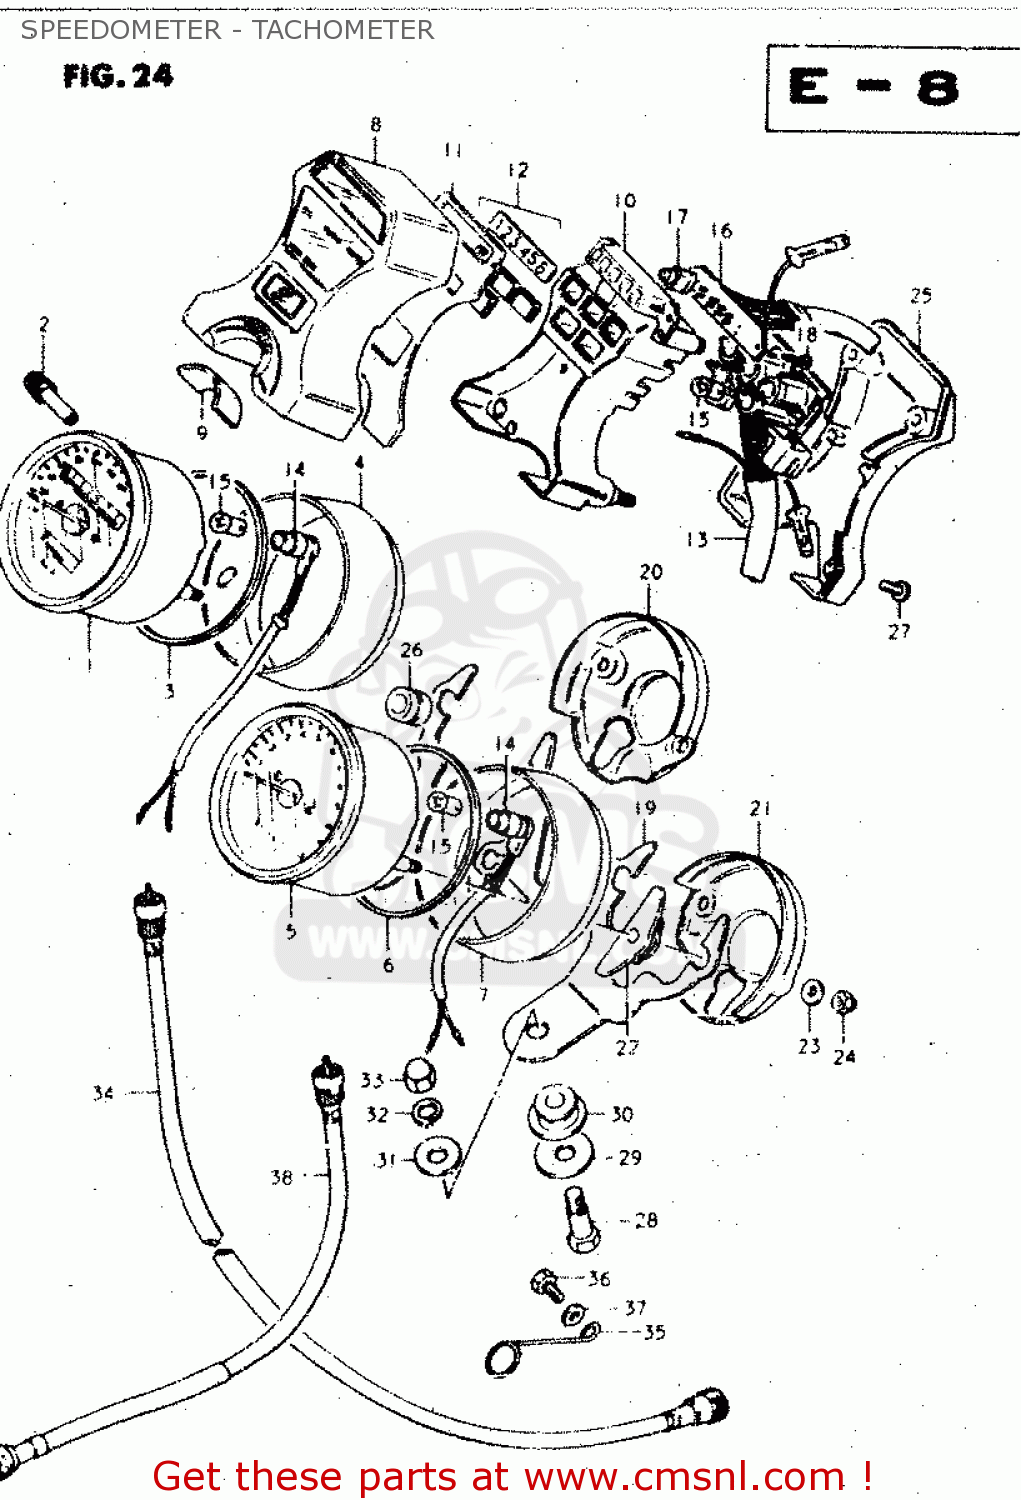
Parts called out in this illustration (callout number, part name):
1	SPEEDOMETER (KILO)
2	KNOB
3	CUSHION
4	COVER,SPEEDOMETER
5	TACH0METER
6	CUSHION
7	COVER,TACHOMETER
8	CASE,PILOT BOX,OUTER
9	SEAL,IGNITION SWITCH
10	CASE,PILOT BOX,INNER
11	PLATE,PILOT BOX
12	LENS SET,PILOT
13	SOCKET
14	SOCKET,METER
15	BULB(12V3.4W,T10)
16	INDICATOR ASSEMBLY,GEAR POSITION
17	BULB(14V1.12W)
18	SCREW
19	BRACKET,COMBINATION METER
20	ORNAMENT,SPEEDOMETER
21	COVER,TACHOMETER
22	CUSHION,METER
23	WASHER
24	NUT
25	COVER,PILOT BOX,UNDER
26	CUSHION,PILOT BOX
27	SCREW,PILOT BOX
28	BOLT(8X31)
29	WASHER
30	CUSHION,METER
31	WASHER(8.5X23X1.2)
32	LOCK WASHER
33	NUT
34	CABLE ASSEMBLY,SPEEDOMETER
35	CLAMP,SPEEDOMETER CABLE
36	BOLT, UPPER
37	WASHER
38	CABLE ASSEMBLY,TACHOMETER
